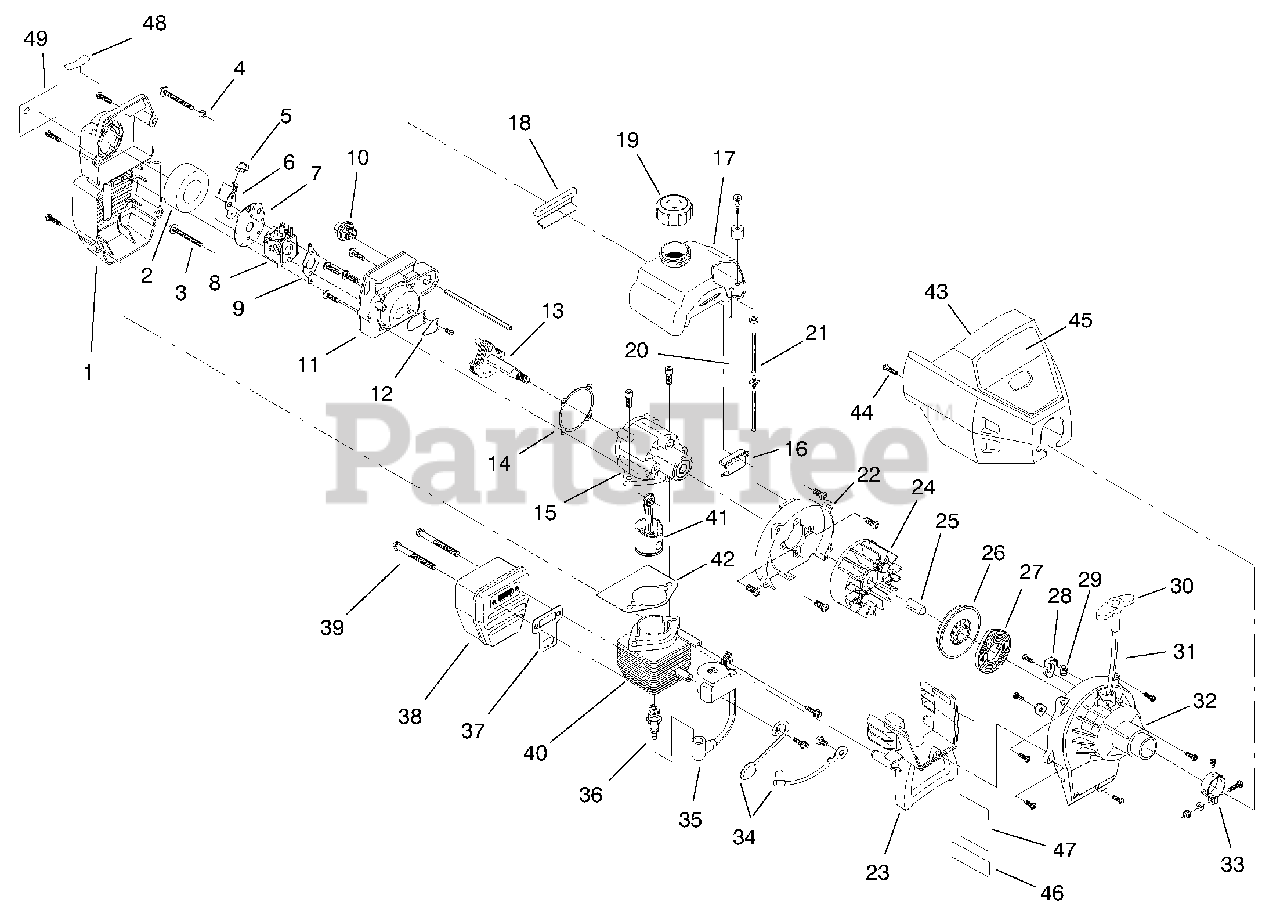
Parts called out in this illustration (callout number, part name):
1	Cover ASM (Includes Ref #2)
2	Filter-Air Cleaner
3	Carburetor Mounting Screw ASM
4	Wavey Washer
5	Choke Lever ASM (Includes Ref #6)
6	Choke Knob & Screw
7	Choke Lever & Plate (Includes Ref #5)
8	Carburetor ASM
9	Gasket-Carburetor
10	Primer & Hose ASM
11	Carburetor Mount ASM
12	Reed ASM
13	Power Shaft ASM
14	Gasket-Carb Mount
15	Crank Case ASM (Includes Ref #13)
16	Mounting Pad-Front
17	Fuel Tank ASM (Includes Ref #19-21)
18	Mounting Pad-Rear
19	Fuel Cap ASM
20	Fuel Line-Return
21	Fuel Line ASM
22	Shroud ASM
23	Shroud Extension
24	Flywheel ASM
26	Pulley-Recoil ASM
27	Spring-Recoil
28	Pulley-Retainer ASM
29	Guide-Rope
30	Pull Handle
32	Housing-Starter ASM
33	Upper Clamp ASM
34	Switch ASM
35	Module ASM
36	Spark Plug
37	Gasket-Exhaust
38	Muffler ASM (Includes Ref #39)
39	Muffler Mounting Bolt Assembly
40	Cylinder ASM
41	Piston & Rod ASM
42	Gasket-Cylinder
43	Cover-Engine
44	Screw-Engine Cover
45	Decal-Toro Housing
46	Decal-Warning, Hot Surface
47	Decal-Carb
48	Decal-Choke Position
49	Decal-Fuel & Oil Mix
